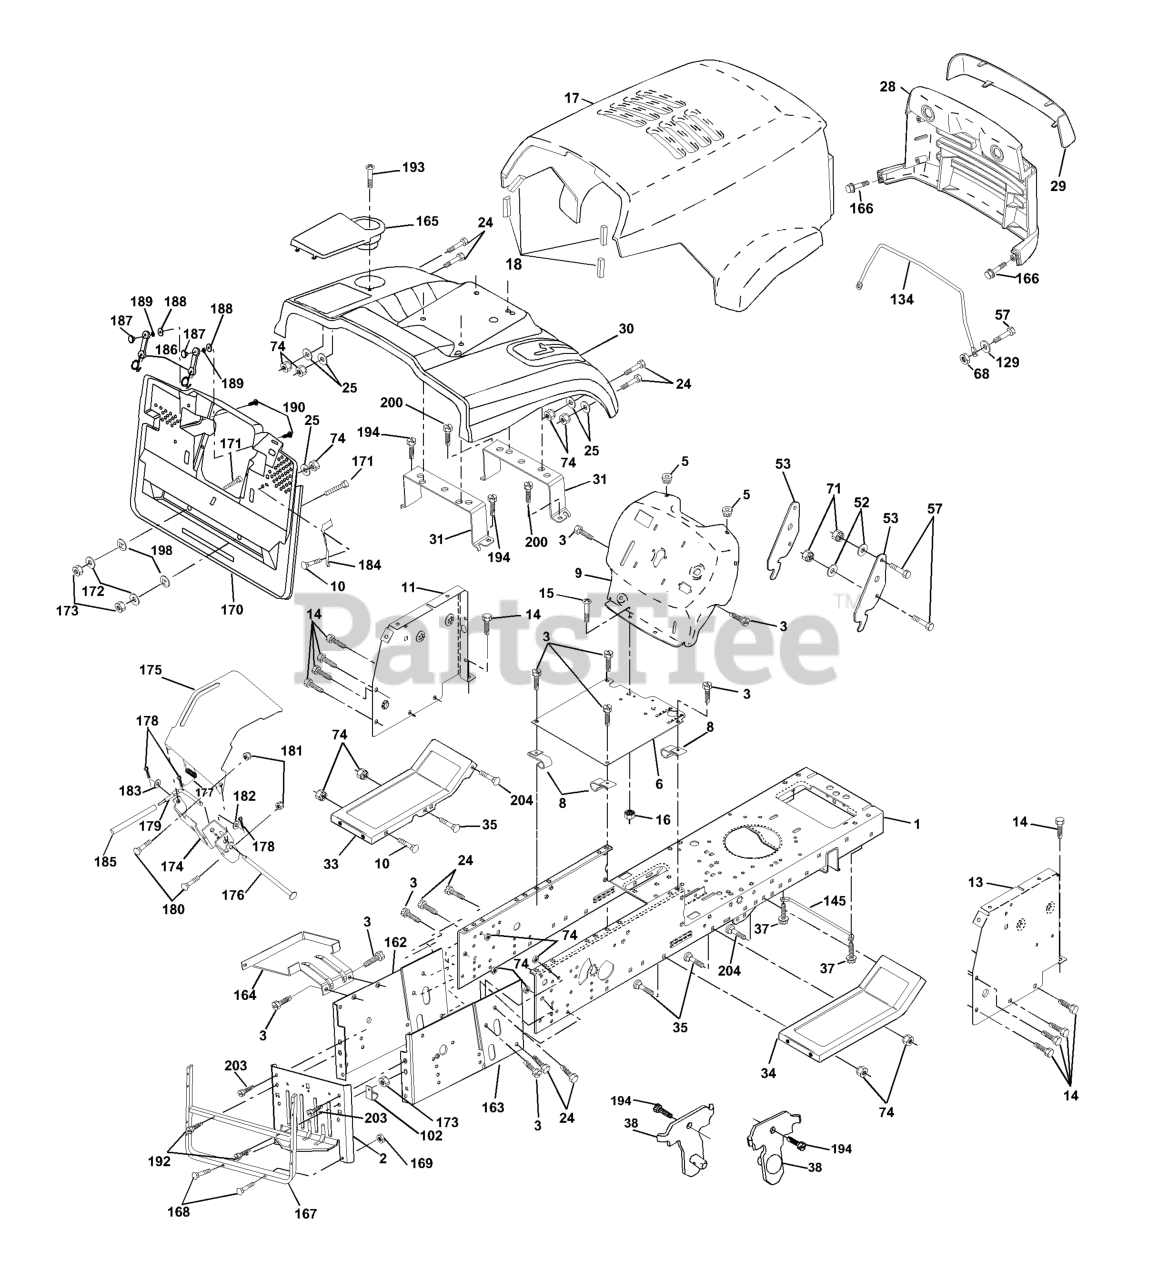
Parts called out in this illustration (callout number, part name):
1	CHASSIS STAMPING
3	SCREW
5	BUMPER.RUBBER.HOOD
6	SADDLE FLAT
8	CLIP,INSULATOR
10	BOLT
11	PANEL DASH LH
13	PANEL DASH
14	SCREW
15	SCREW
16	NUT
17	HOOD
18	BUMPER HOOD T
24	BOLT
25	BOLT
28	GRILL
29	LENS
30	FENDER
31	BRACKET SUPPORT FENDER
33	FOOT REST LH
34	FOOTREST RH
35	BOLT
37	SCREW
38	BRACKET
51	LOCKNUT.NYLOC.1/4-20
52	WASHER
53	BRACKET PNT PICK OFF LT/PL
57	BOLT
68	NUT
74	NUT
102	CLIP T
129	WASHER
134	ROD SUPPORT HOOD LT/PL HUS.
145	ROD PIVOT CHASSIS/HOOD
165	COVER BATTERY
166	SCREW
167	SUPPORT.ASM.BACKPLATE
168	BOLT
169	NUT LOCK
170	COVER BACKPLATE
171	BOLT
172	WASHER
173	NUT
176	HINGE PIN
177	SPRING COVER LH
178	PIN COTTER
180	BOLT
181	NUT
182	WASHER
183	WASHER
185	TUBE LEVER
186	LATCH ASSY
187	NUT
188	WASHER
189	WASHER
190	SCREW
192	SCREW
193	SCREW
194	SCREW
203	SCREW
204	SCREW
